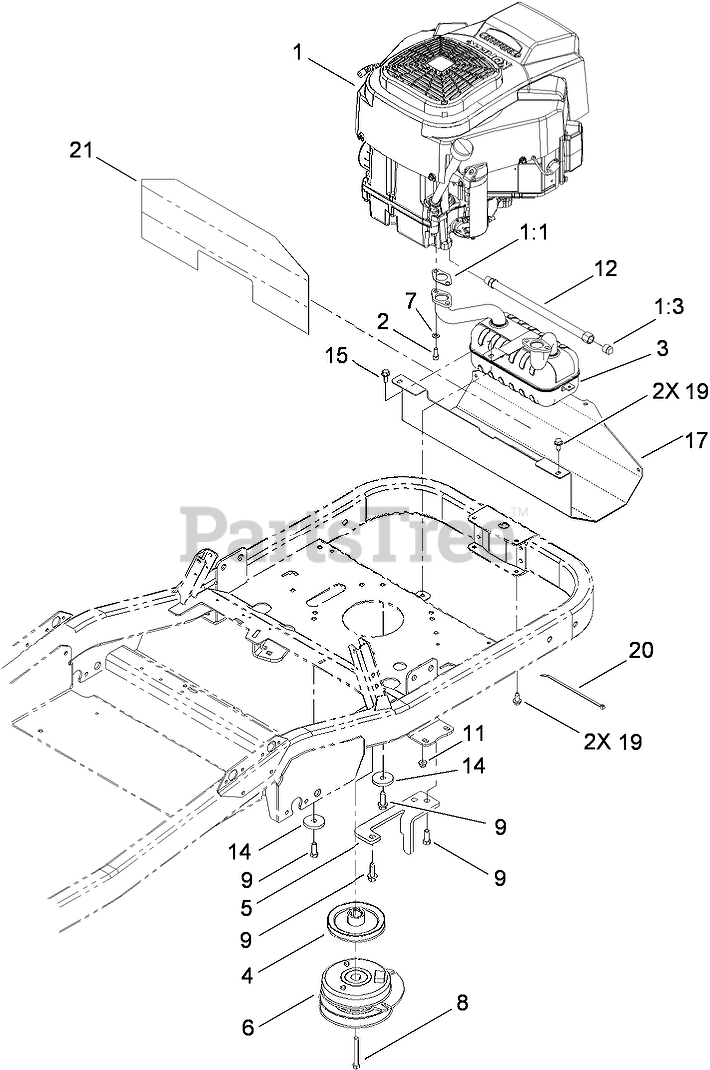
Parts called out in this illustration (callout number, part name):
1:1	GASKET-EXHAUST
1:3	PLUG-PIPE, SQH
2	SCREW-HSH
3	MUFFLER-TWIN, KOHLER
4	PULLEY-ENGINE
5	BRACKET-STOP, PTO
6	CLUTCH-PTO
7	WASHER-LOCK
8	SCREW-HH
9	SCREW-TAPTITE
11	NUT-HF, NI
12	HOSE-DRAIN, OIL
14	WASHER-PLAIN
15	SCREW-HHF
17	SHIELD-HEAT
19	SCREW-HWHTF
20	TIE-CABLE
21	FOIL-HEAT SHIELD
